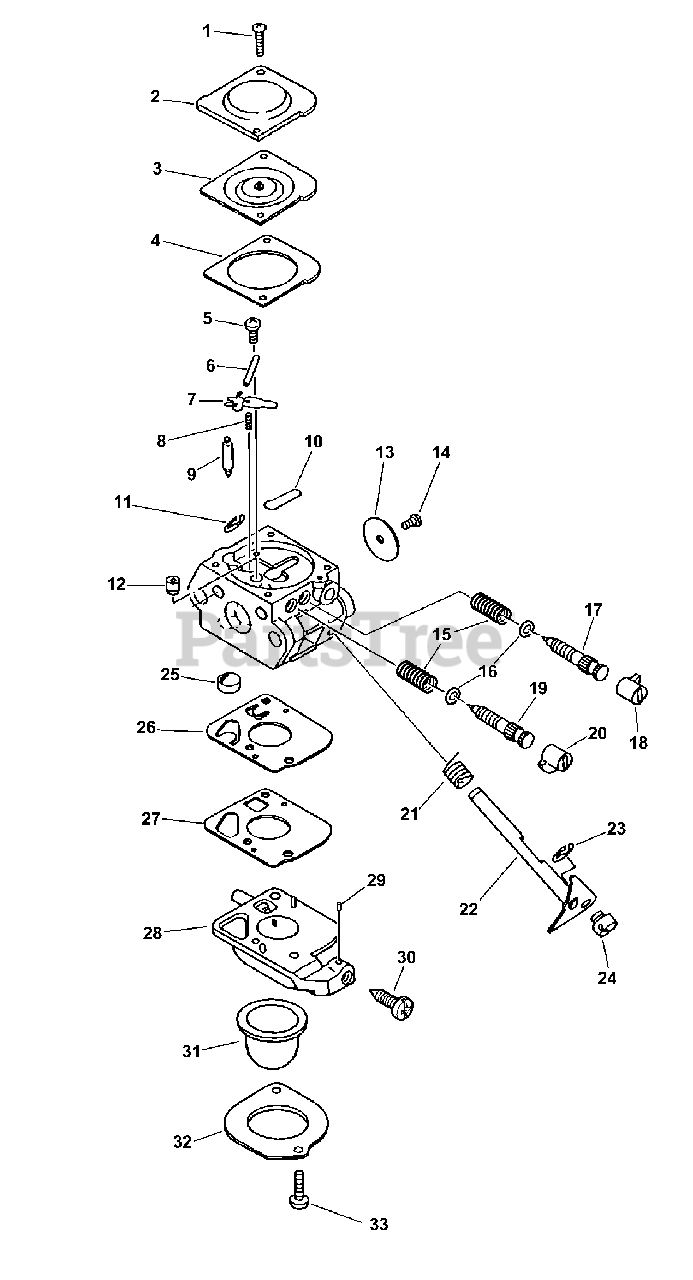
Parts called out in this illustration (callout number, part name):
1	SCREW
2	COVER, METERING
3	DIAPHRAGM, METERING
4	GASKET, METERING
5	SCREW, METERING LEVER PIN
6	PIN, METERING LEVER
7	LEVER, METERING
8	SPRING, METERING LEVER
9	VALVE, INLET NEEDLE
10	PLUG, WELCH
11	RING, RETAINING
12	NOZZLE, CHECK VALVE
13	VALVE, THROTTLE
14	SCREW
15	SPRING
16	WASHER
17	NEEDLE - LOW SPEED
18	CAP, LIMITER
19	NEEDLE - HIGH SPEED
20	CAP, LIMITER
21	SPRING, RETURN
22	SHAFT, THROTTLE
23	RING, RETAINING
24	SWIVEL
25	STRAINER
26	DIAPHRAGM, PUMP
27	GASKET, PUMP
28	BASE, PURGE
29	PIECE, FRICTION
30	SCREW, IDLE ADJUST
31	BULB, PURGE
32	RETAINER, PURGE BULB
33	SCREW, RETAINER
